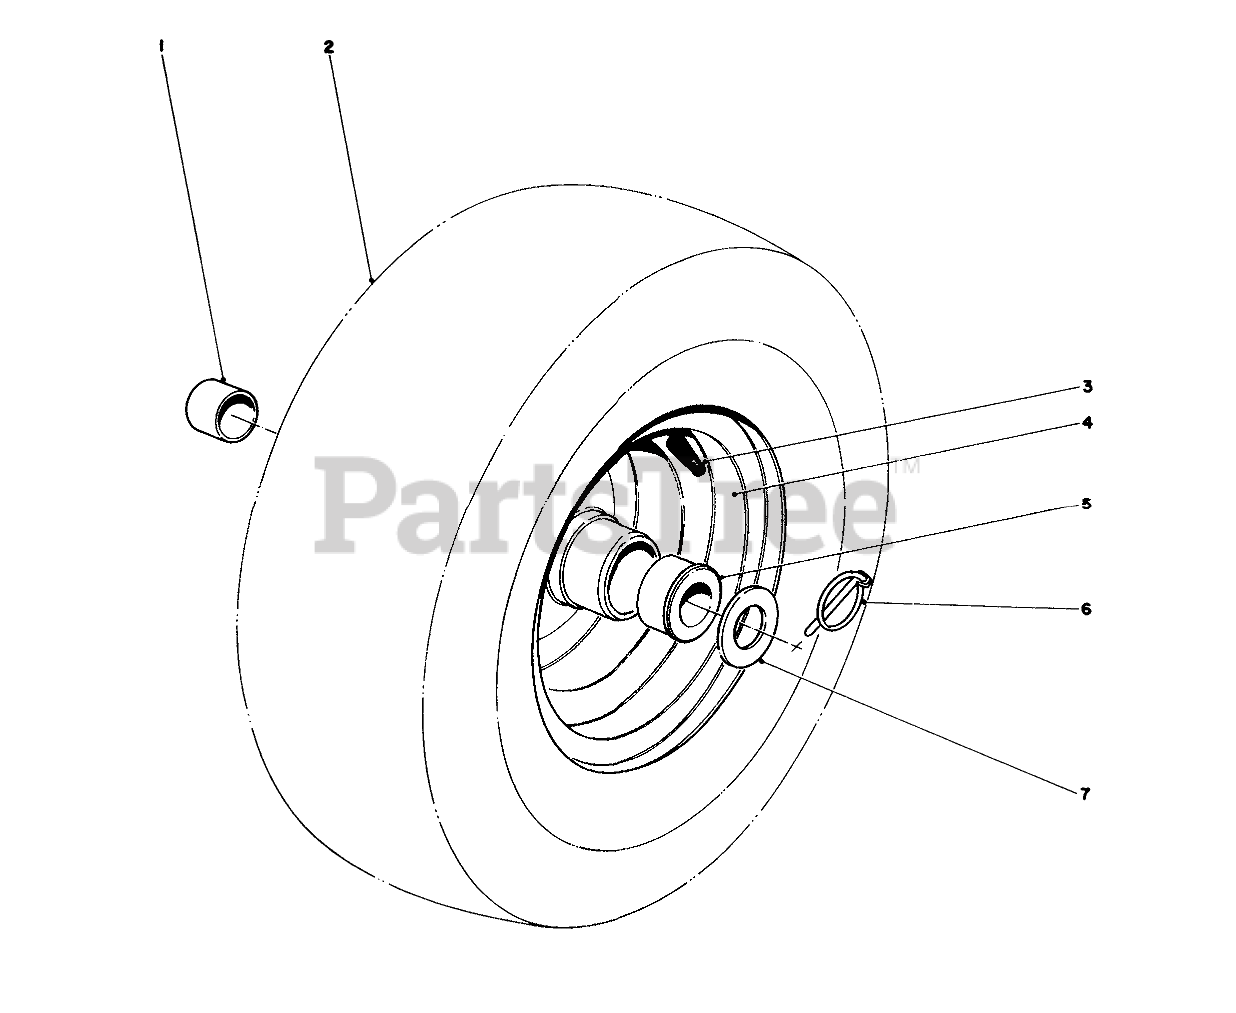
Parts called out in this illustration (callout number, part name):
1	.877ID X .750LG BSHG
2	Tire
3	STEM-VALVE
4	Wheel & Hub Assembly (Incl. Ref. #1 & 5)
5	BUSHING
6	PIN-LYNCH
7	WASHER-THRUST
